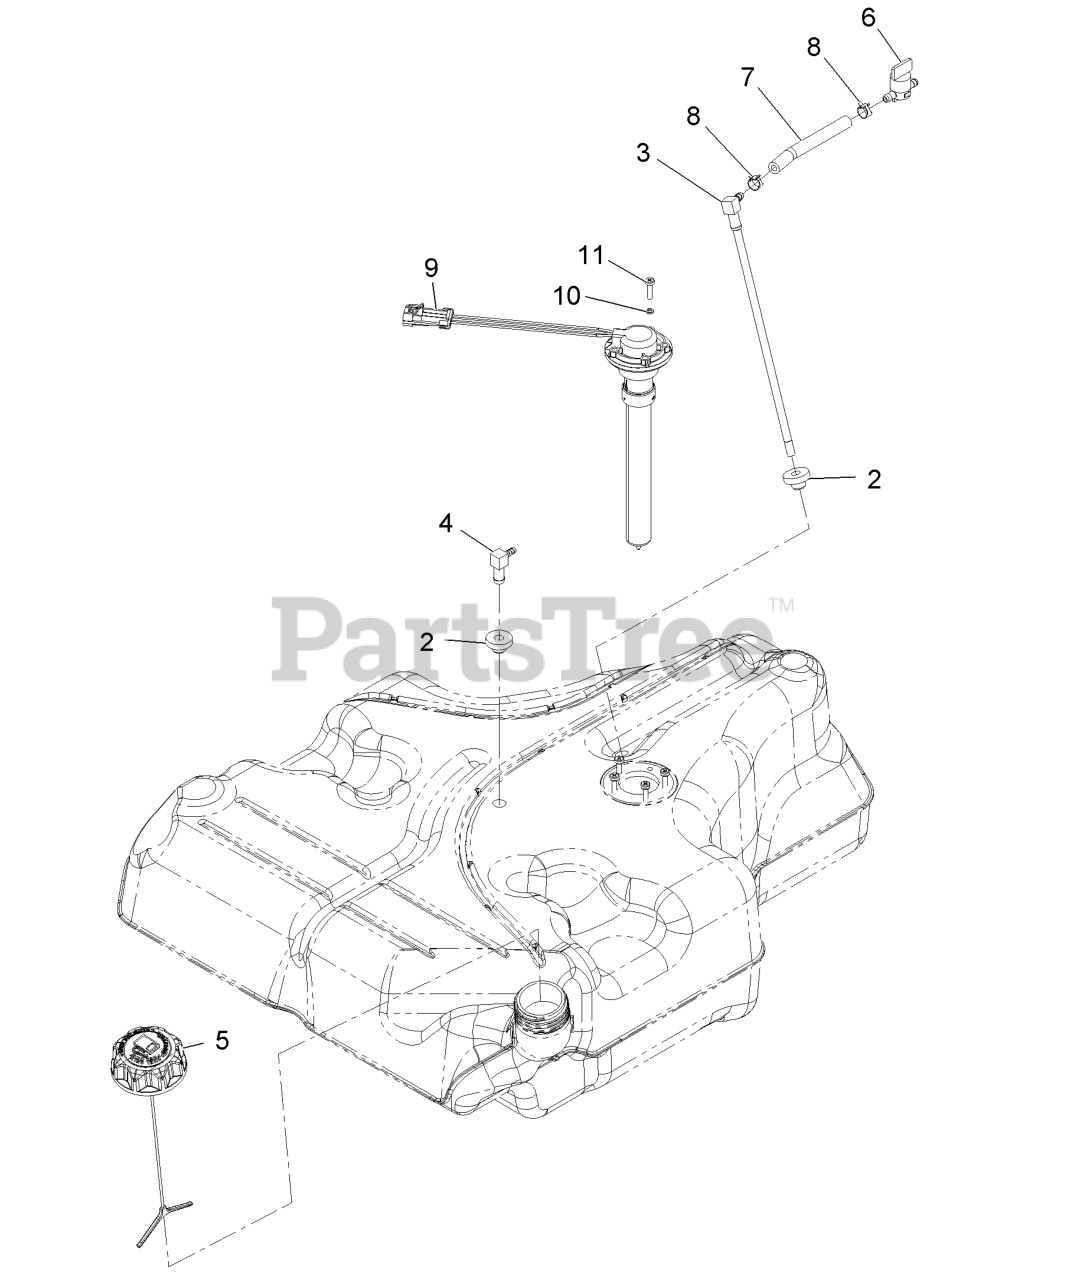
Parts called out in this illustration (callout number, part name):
2	BUSHING
3	FUEL LINE KIT (WITH GROMMET)
4	FITTING-90 ELBOW
6	VALVE-FUEL
7	HOSE-FUEL
8	CLAMP-HOSE
10	WASHER-LOCK
11	SCREW-PAN
